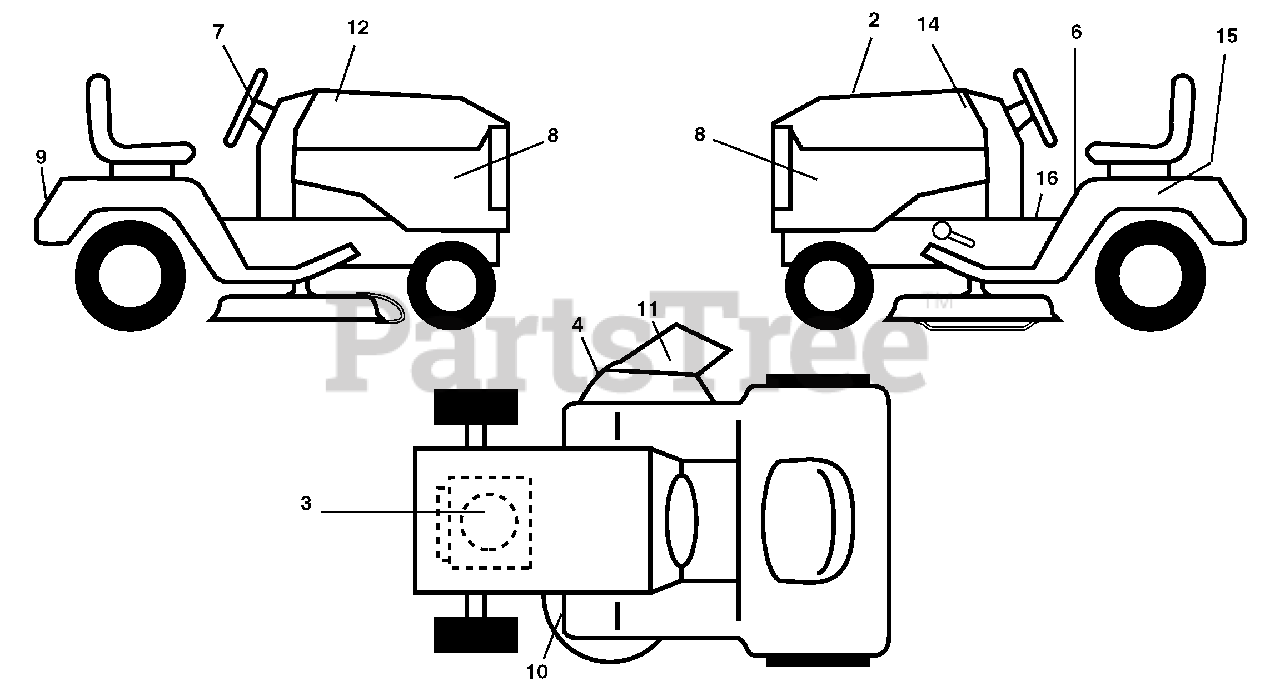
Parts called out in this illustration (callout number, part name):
2	Decal, Replacement
3	Decal, Engine HP
4	Decal Warning
6	Decal, Fender Danger English
7	Decal Ins Str Wh
8	Decal, Side Panel
9	Decal, Fender
10	Decal, V-Belt Sch.
12	Decal, Hood RH
14	Decal, Hood LH
15	Decal, Caution, Battery
16	Decal, Oper
16	Decal Bypass
16	Decal, Handle Lft Height Adj.
16	Manual, Operator's (E&F)
16	Manual, Parts (E&F)
